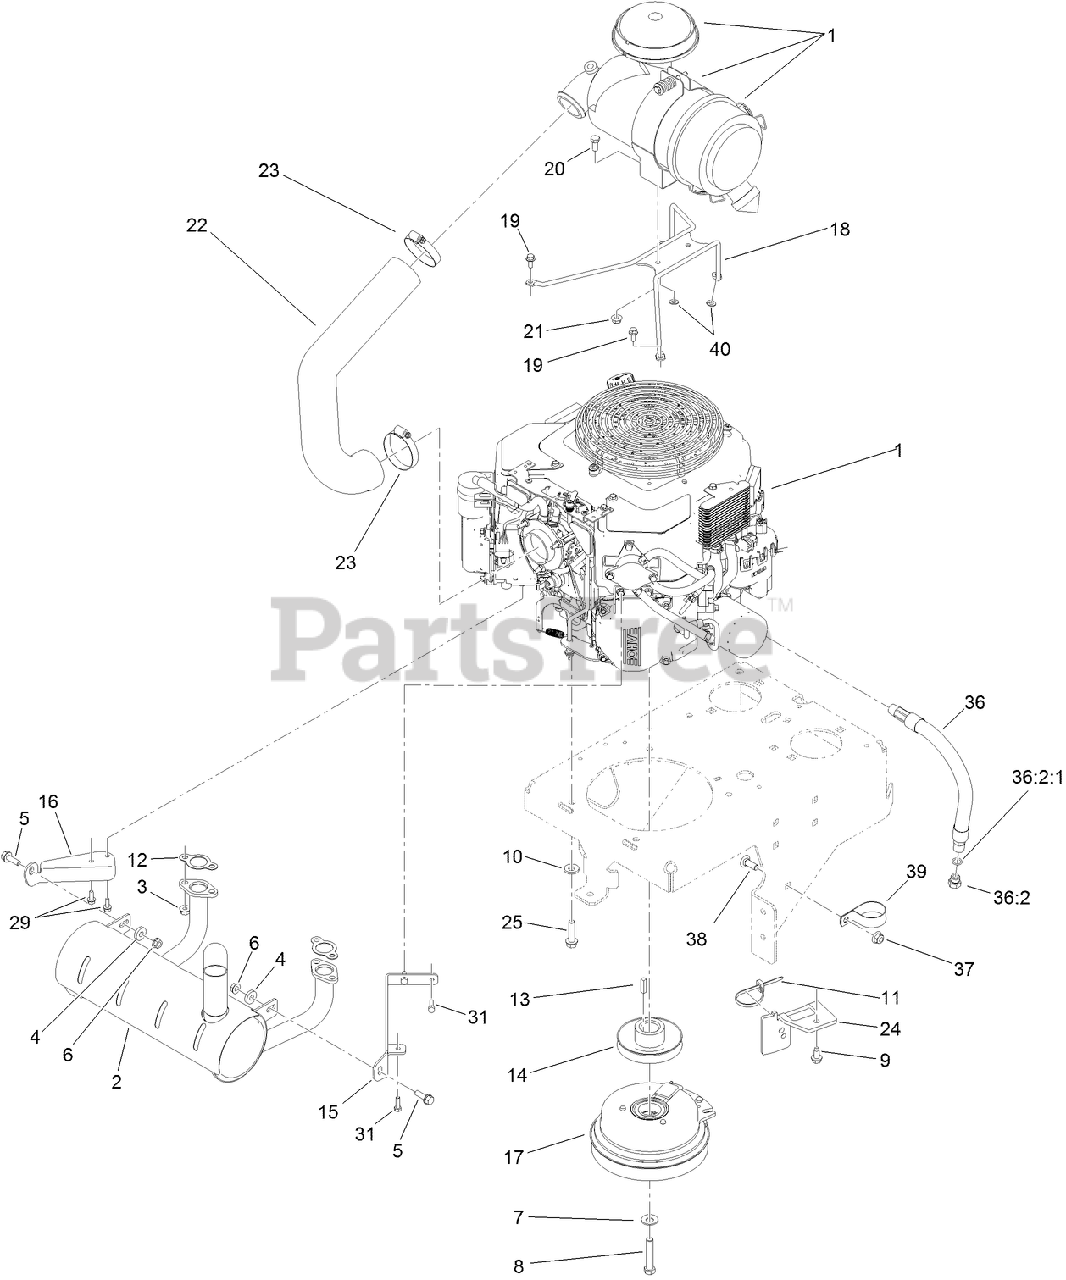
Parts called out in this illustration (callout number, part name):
2	MUFFLER
3	NUT-FLANGE
4	SPACER
5	SCREW-HHF
6	NUT-HF
7	WASHER-SPRING
8	SCREW-HH
9	SCREW-HWHTF
10	WASHER-BELLEVILLE
11	TIE-CABLE
12	GASKET-EXHAUST
14	PULLEY
15	BRACKET-MUFFLER, LH
16	BRACKET-MUFFLER, RH
17	CLUTCH-200CMS
18	MOUNT-CLEANER, AIR
19	SCREW-HHF
20	SCREW-HH
21	NUT-HF, NI
22	HOSE-INTAKE, AIR
23	CLAMP-HOSE
24	BRACKET-ANCHOR, CLUTCH
25	SCREW-HWH
29	SCREW-HWHTF
31	SCREW-HH
36	OIL DRAIN HOSE ASM
36:2	PLUG-HH
36:2:1	O-RING
37	NUT-HF, NI
38	SCREW-CARR
39	CLAMP-R
40	WASHER-PLAIN
